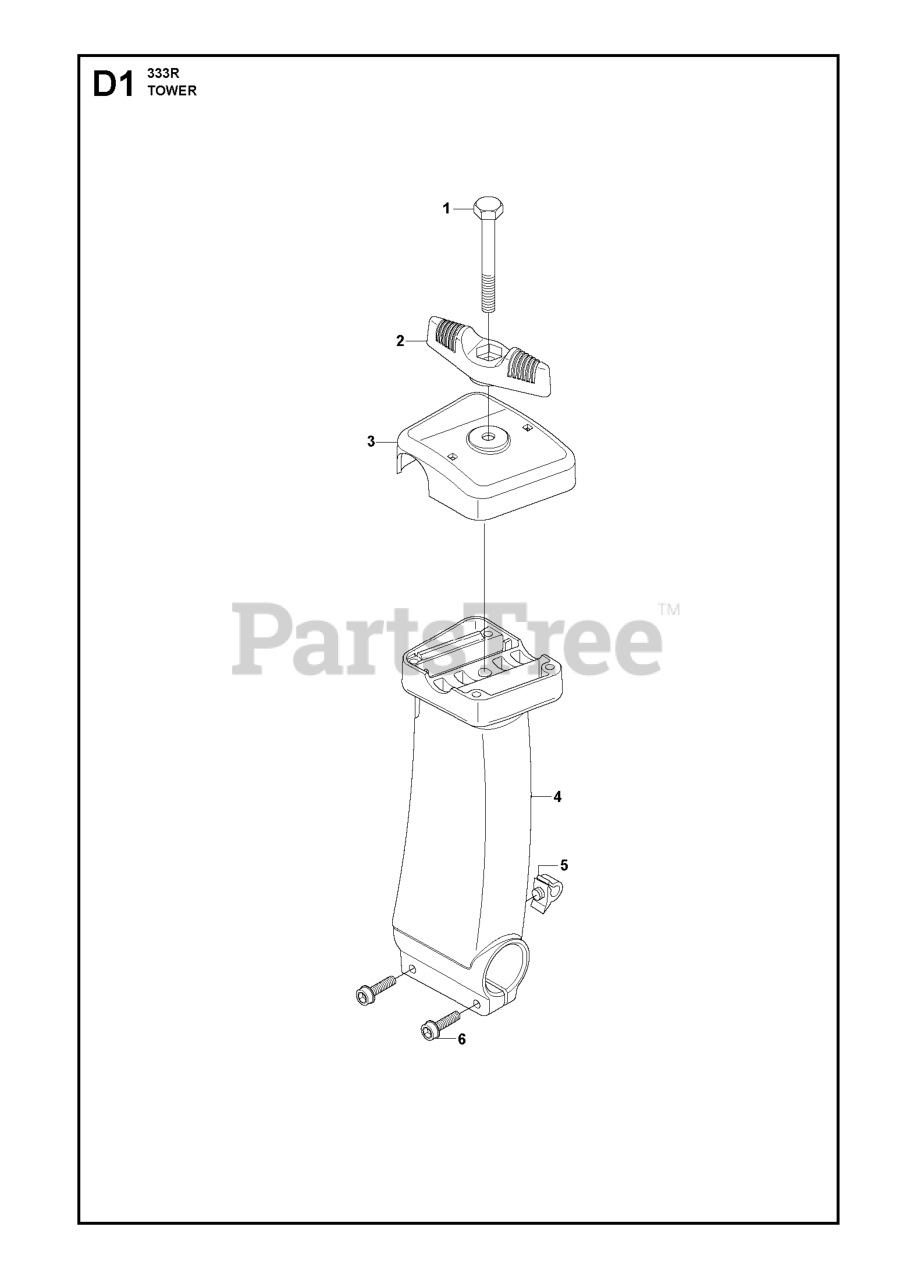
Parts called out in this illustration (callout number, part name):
1	%SCREW
3	PROTECTOR CLAMP
6	SCREW IHSCM
